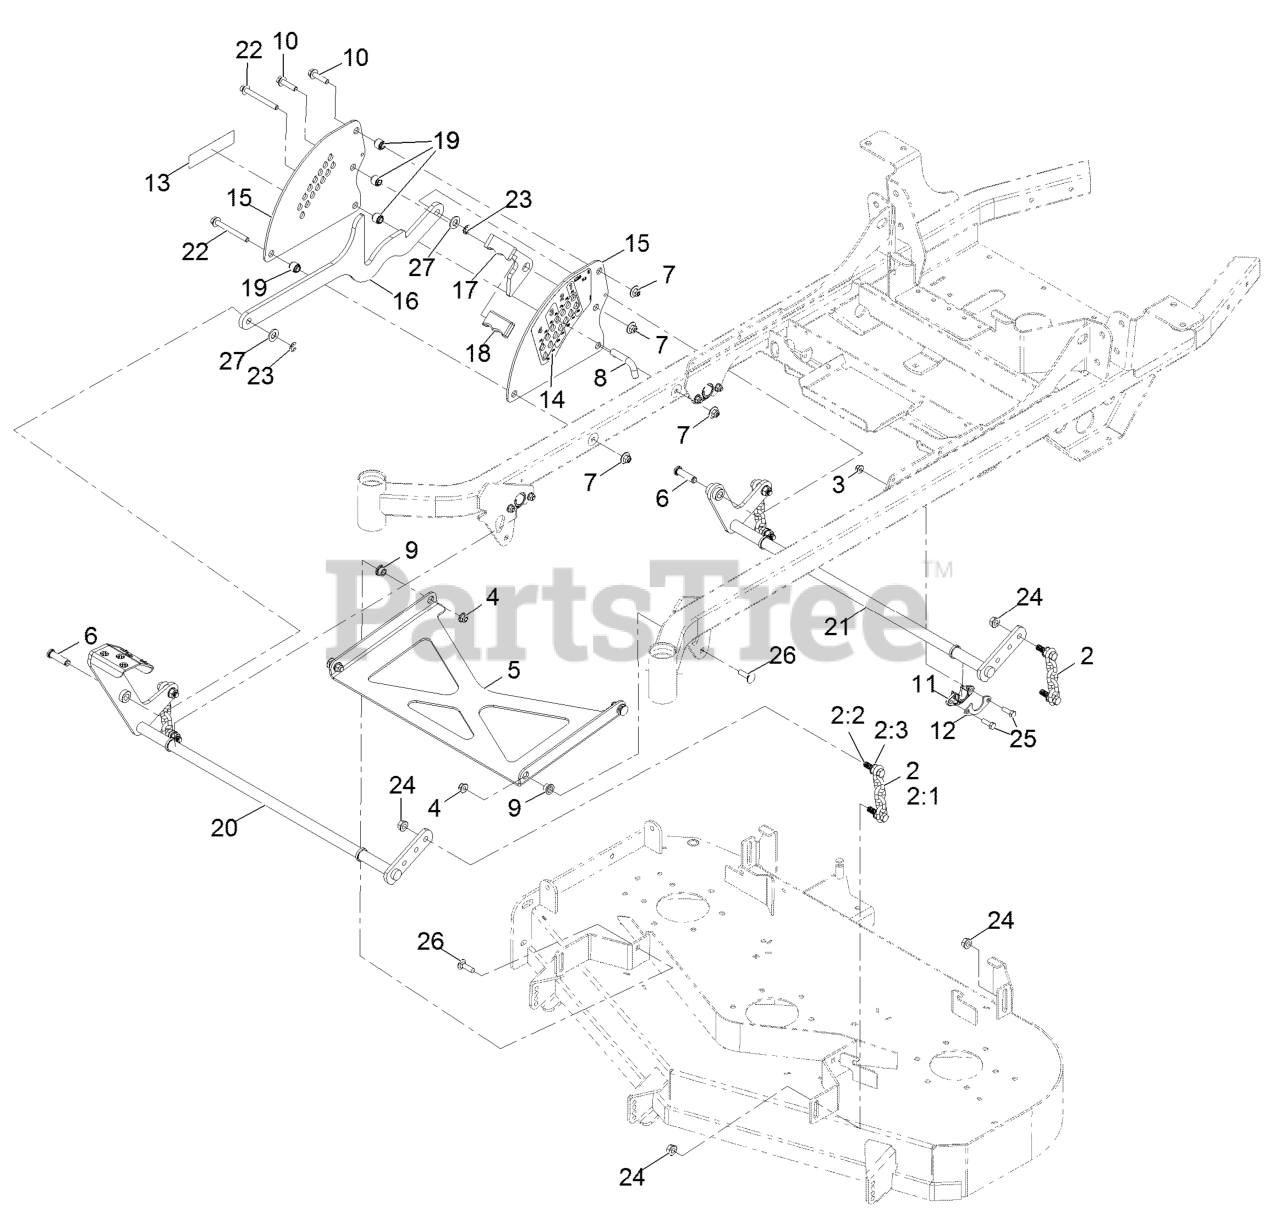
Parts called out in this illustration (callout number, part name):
2	DECK CHAIN ASM
2:1	CHAIN-LIFT, DECK
2:2	SCREW-HH
3	NUT-HF, NI
4	NUT-HF, NI
5	STRUT-DECK
6	PIN-CLEVIS
7	Nut-Nyloc 3/8-16 Flg
8	PIN-HOC
9	BUSHING-FLANGED
10	SCREW-HHF
11	BUSHING-FLANGE
12	GUSSET-LIFT, DECK
13	DECAL-S-SERIES
14	DECAL-HEIGHT OF CUT
15	PLATE,DECK LIFT
17	TRANSPORT LOCK-HOC
18	GRIP-FLAT
19	SPACER-STEP, DOUBLE
20	WLD-DECK LIFT SHAFT FRT
21	WLD-DECK LIFT SHAFT RR
22	SCREW-HHF
23	RING-RETAINING, EXTERNAL
25	SCREW-HH
26	BOLT-CARR
27	WASHER-FLAT
